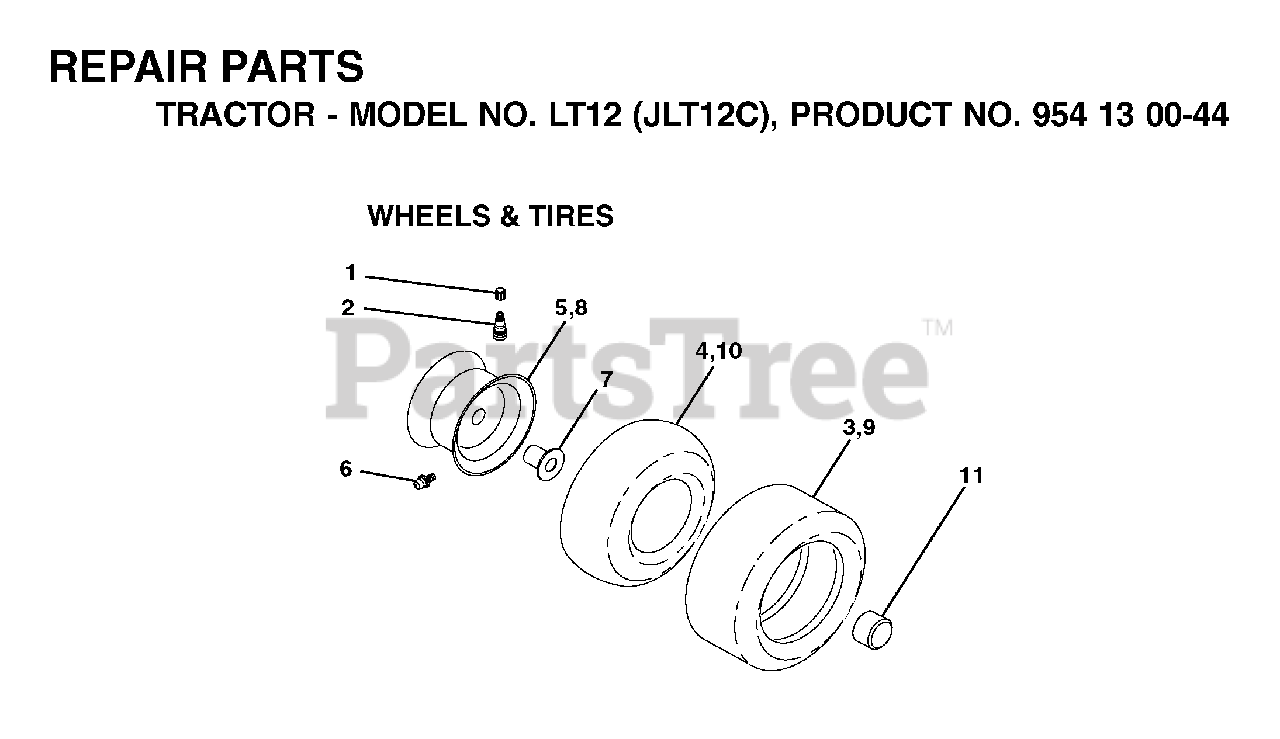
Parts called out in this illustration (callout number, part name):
1	VALVE CAP
2	VALVE STEM LT
3	TIRE HEAVY DUTY
4	TUBE.5.3/4.5/6
5	RIM ASM 6" FRONT SILVER
6	FITTING LT
7	BEARING T
8	RIM ASM 8" REAR SILVER
9	TIRE
10	TUBE
11	CAP, AXLE BLK
